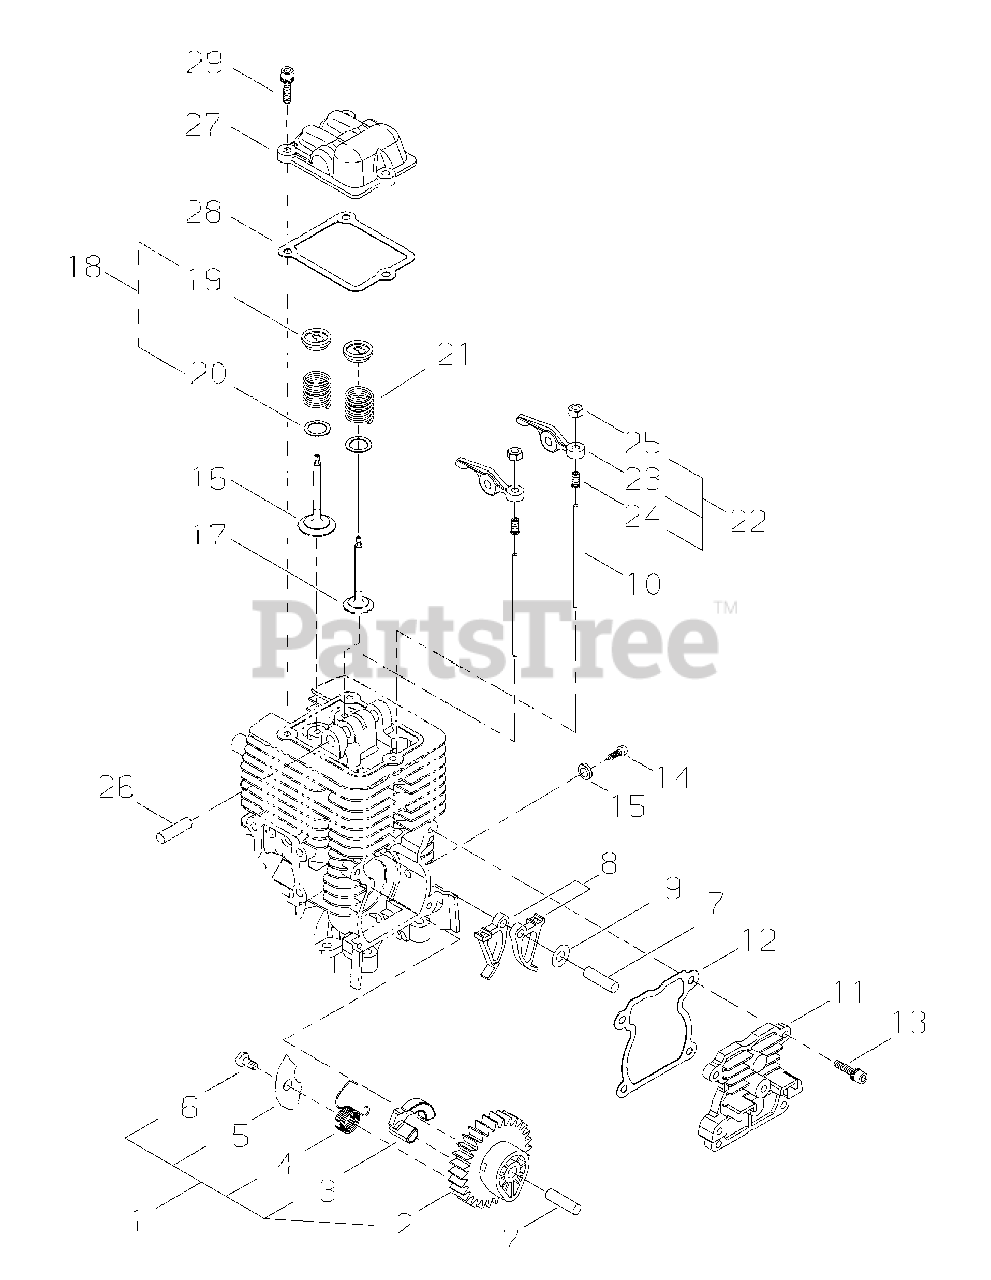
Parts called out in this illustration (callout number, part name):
1	CAM GEAR ASSY
2	GEAR, CAM
3	WEIGHT
4	SPRING
5	COVER, PLATE
6	SCREW - 4X6 -- TAPPING
7	PIN - LOCATING
8	FOLLOWER, CAM
9	WASHER - 5
10	PUSHROD
11	COVER, CAM GEAR
12	GASKET
13	SCREW - 4X14
14	SCREW - 5
15	WASHER
16	VALVE, INTAKE
17	VALVE, EXHAUST
18	VALVE RETAINER ASSY
19	RETAINER, VALVE
20	WASHER, VALVE - 9
21	SPRING, VALVE
22	ROCKER ARM ASSY
23	ARM, ROCKER
24	SCREW, ADJUST
25	LOCKNUT, ADJUSTER
26	SHAFT, ROCKER ARM - 5X37.8
27	COVER, ROCKER ARM
28	GASKET
29	SCREW - 4X14
